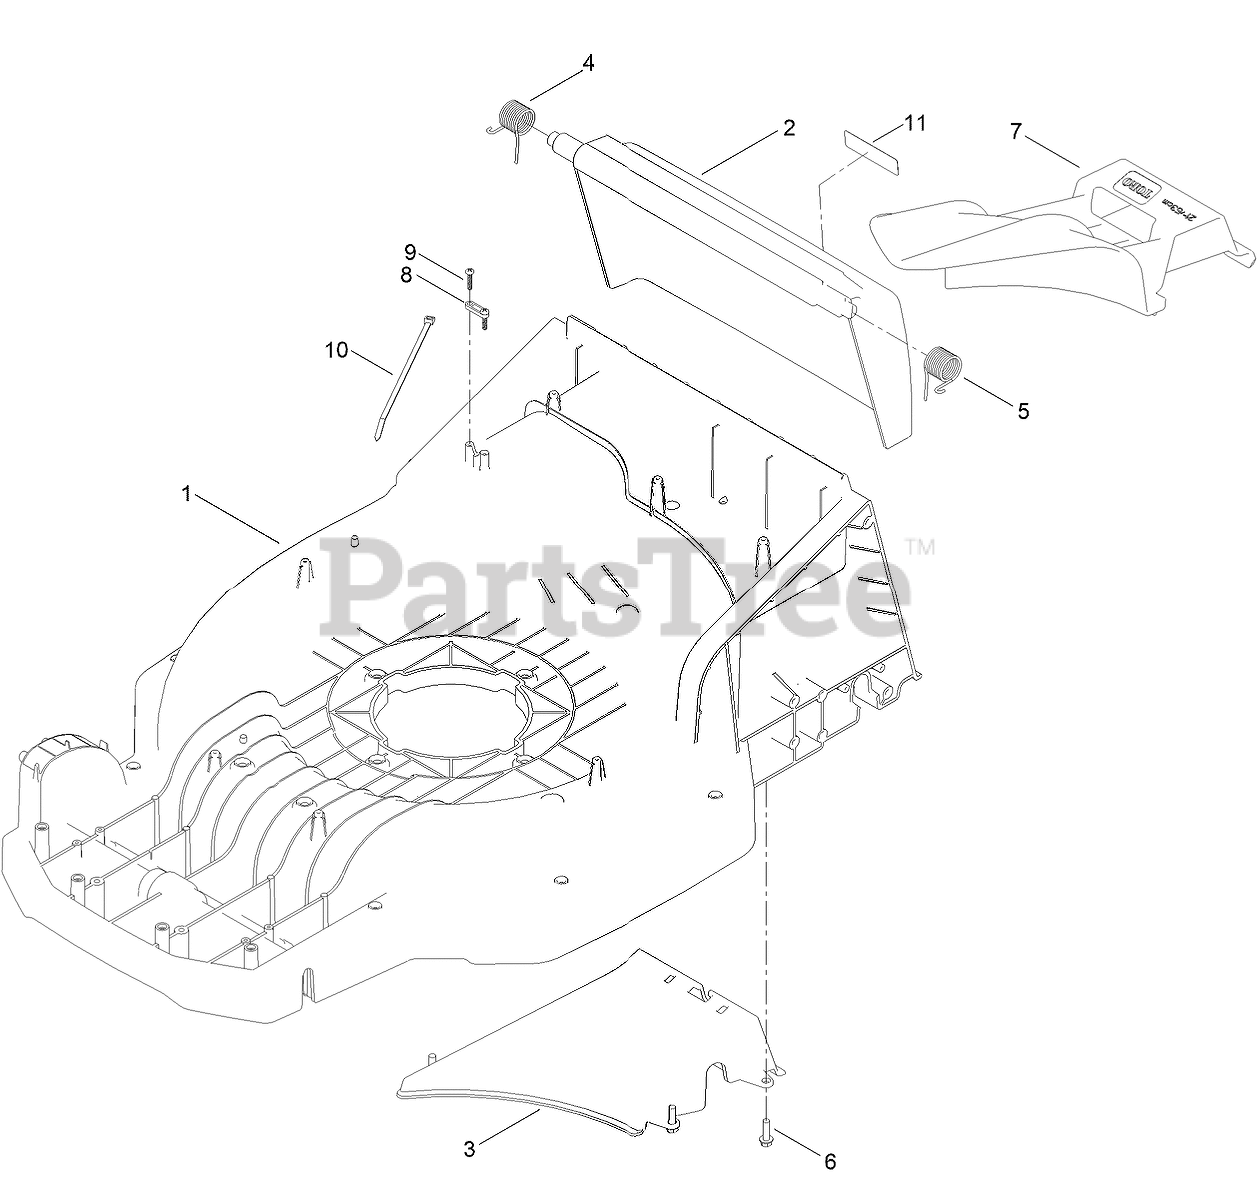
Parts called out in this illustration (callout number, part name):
1	DECK-PLASTIC, 21"
2	ASM-REAR DOOR, IN-MOLD (60V)
3	RAMP-DISCHARGE
4	SPRING-TORSION, RH
5	SPRING-TORSION, LH
6	SCREW-HWH
7	PLUG-DISCHARGE
8	CLAMP-HARNESS
9	SCREW-PPH
10	TIE-CABLE
11	DECAL-PROP 65, SHORT, TRILINGUAL
